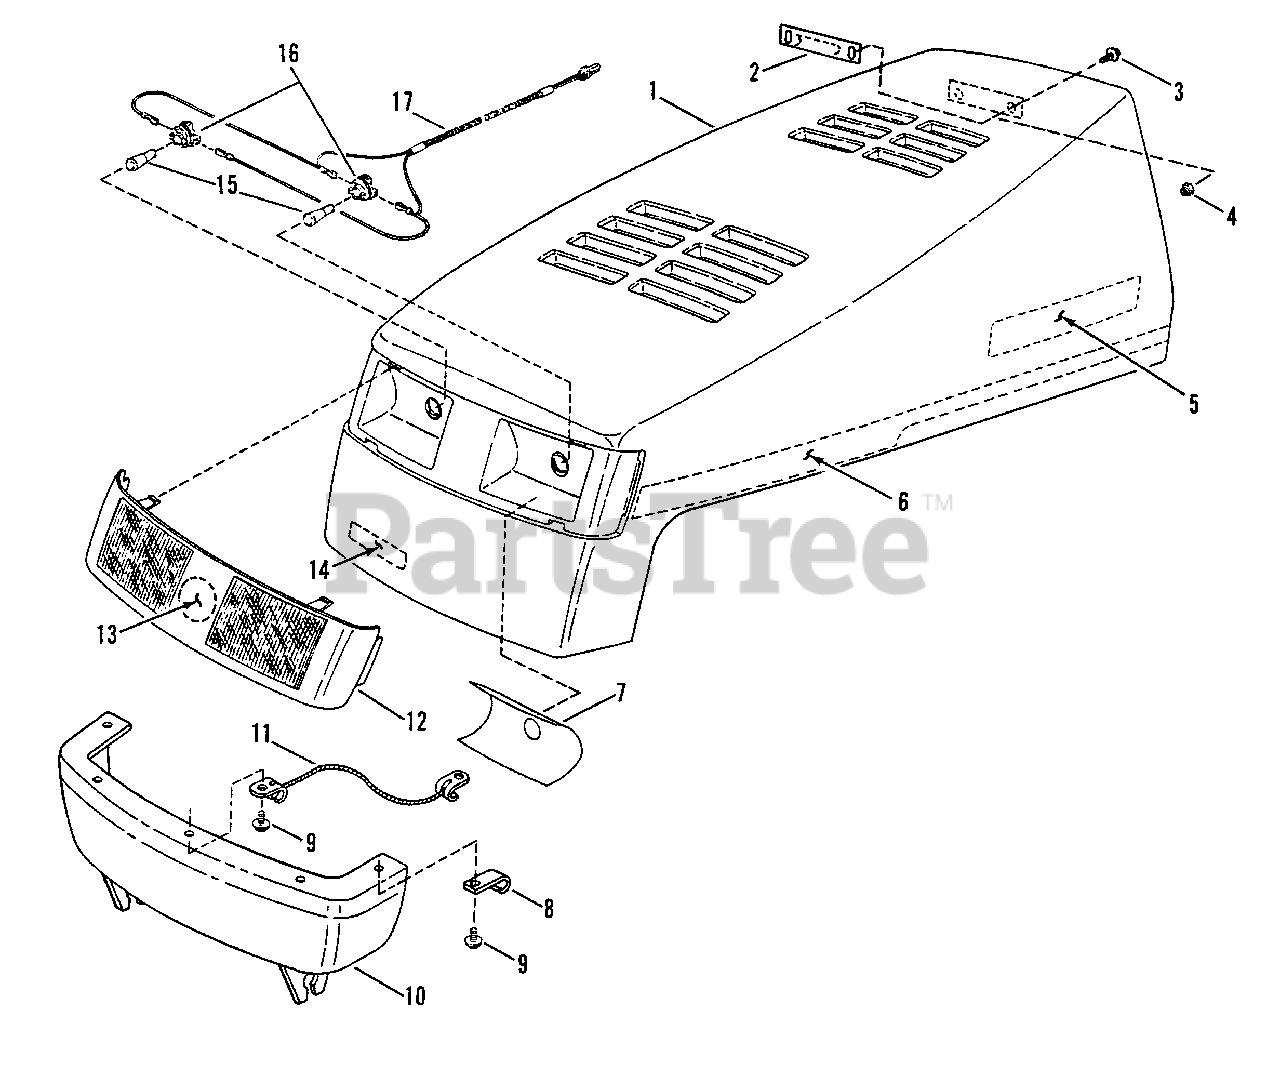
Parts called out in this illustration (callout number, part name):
1	HOOD Assembly
2	LATCH, Spring
3	SCREW, 1/4-20 x 5/8" Truss Hd., Torx
4	NUT, 1/4-20 Hex Nyloc
5	DECAL - SNAPPER, 8" Molded Logo, White Letters
5	DECAL - SNAPPER, 8" Molded Logo, Silver Letters
6	DECAL, Hood, Right Side
6	DECAL, Hood, Left Side
7	DECAL, Lens, Right Side
7	DECAL, Lens, Left Side
8	CLIP, "J"
9	SCREW, M4.8 x 1.59 x 16.00mm
10	BUMPER, Front
11	LANYARD, Hood
12	LENS, Clear
13	DECAL, Molded Medallion, Convertible Mower
14	DECAL - SNAPPER, 4" Molded Logo, White Letters
15	BULB, Headlights
16	SOCKET, Headlight Bulb
17	HARNESS, Headlight Wiring
